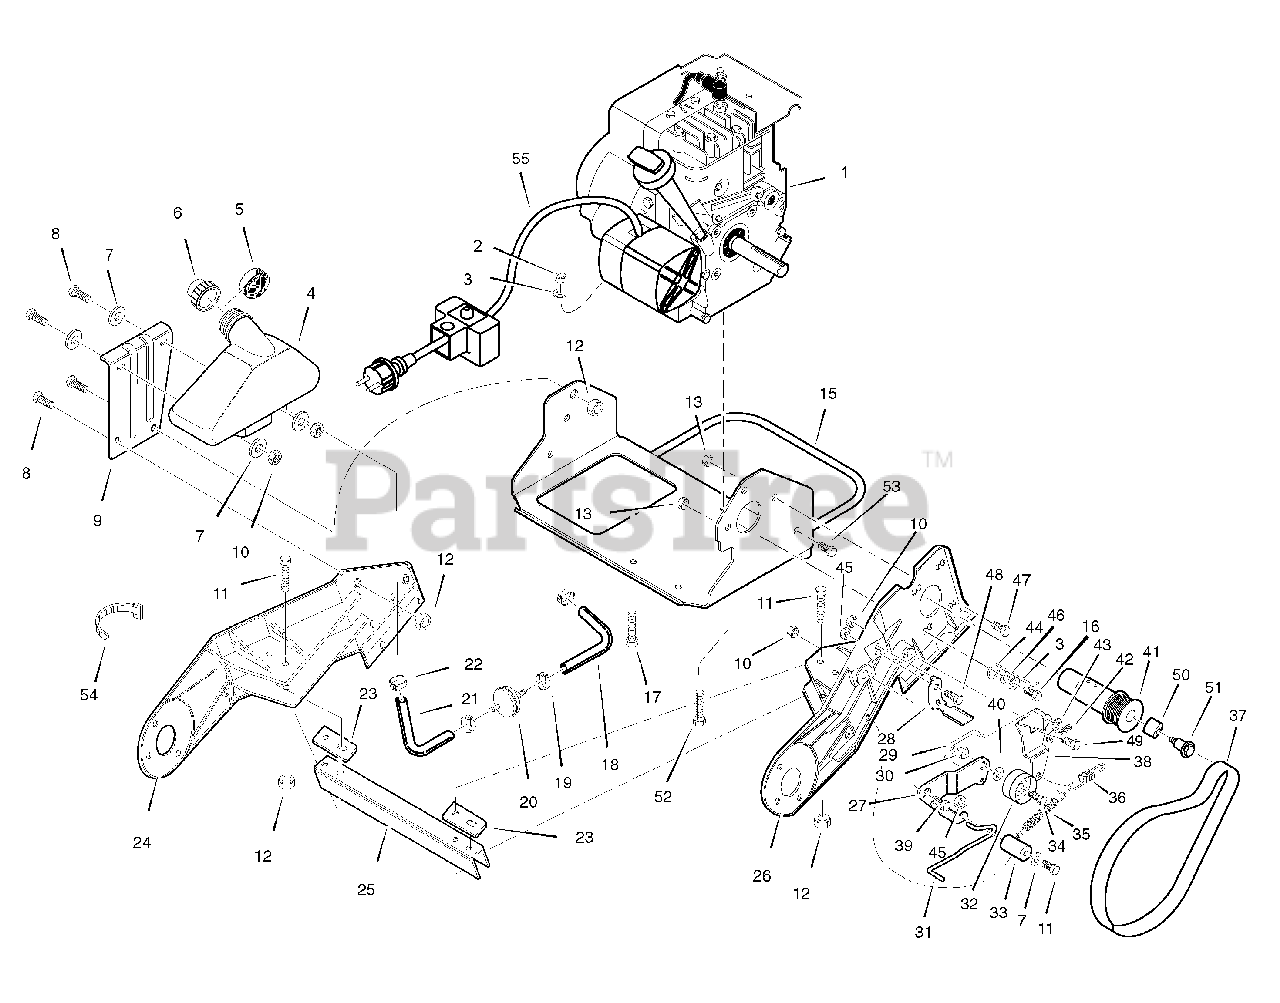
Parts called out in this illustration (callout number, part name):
2	NUT, 5/16-18
3	WASHER, Split Lock, 5/16 x 37/64
4	TANK, Fuel 1.5QT
5	RING, Foam, Fuel Tank
6	CAP, Fuel
7	WASHER, Flat
8	SCREW, 1/4-20 x 3/4
9	BRACKET, Fuel Tank
10	NUT, Hex, 8-32
11	SCREW, 1/4-20 x 2
12	NUT, Hex, 1/4-20
13	NUT, Hex, Control Lock, 5/16-18
15	ASSEMBLY, Cradle
16	BOLT, 5/16-18 x 3/4
17	BOLT, Engine Mount
18	HOSE, FUEL, 12"
19	CLAMP, Fuel Line
20	FILTER, Fuel
21	HOSE, Fuel, 12"
22	CLAMP, Hose Screw
23	PLATE, Bolting Support
24	FRAME, R.H.
25	CHANNEL, Frame Support
26	FRAME, L.H.
27	BRACKET, Idler Arm
28	BRAKE PAD
29	ROD, Clutch Linkage
30	NUT, Control Lock, 3/8-16
31	WIRE, Brake
32	PULLEY, Idler
33	ROLLER, Pinch
34	SCREW, 3/8-16 x 1-1/2
35	SPRING, Extension, 3/8 OD x 2-1/2
36	SPRING, Extension, 3/4 OD x 2
37	BELT, 35-9/64"
38	ARM, Idler Pivot
39	BOLT, Shoulder, 5/16-18 x 1/2
40	WASHER, Flat
41	PULLEY, Engine
42	PIN, Cotter
43	WASHER, Flat, #8
44	GUIDE, Belt
45	NUT, 1/4-20
46	WASHER, 11/32 x 11/16 OD
47	SCREW, 5/16-18 x 5/8
48	SCREW, 1/4-20 x 5/8
49	SCREW, 8-32 X 3
50	SPACER, Drive Pulley
51	BOLT, Engine Pulley
52	BOLT, 5/16-18 x 7/8
53	SCREW, 1/4-20 x 5/8
54	TIE, Cable
55	CORD, Electric, 10FT, 220V
